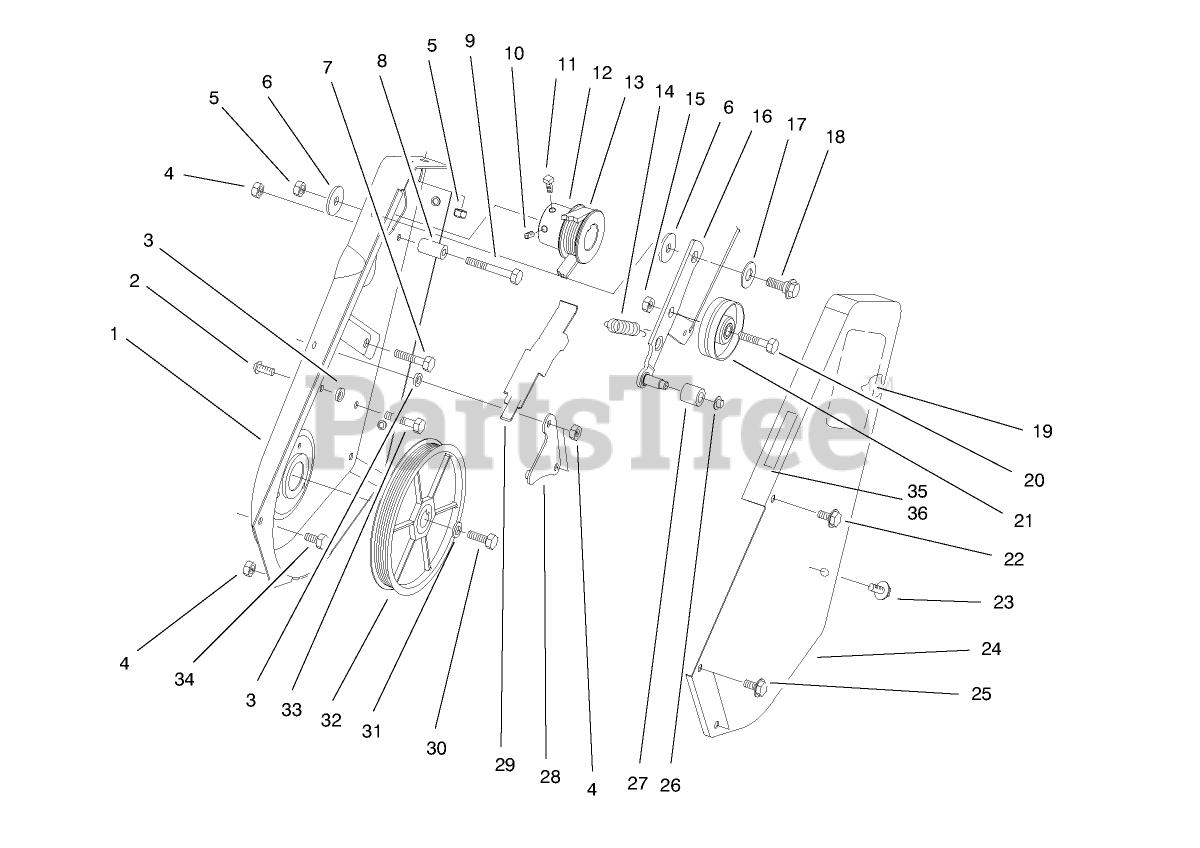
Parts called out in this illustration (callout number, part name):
2	SCREW-HSBH
3	SPACER-PLATE, PIVOT
4	NUT-LOCK, NI
5	NUT-LOCK, NI
6	WASHER-PIVOT
7	SCREW-HH
8	SLEEVE-GUIDE, BELT
9	SCREW-HH
10	SCREW-HSH
11	SCREW-SQH
12	ENGINE PULLEY
13	BELT - DRIVE
14	SPRING-EXTENSION
15	NUT-LOCK, CONE
16	IDLER ARM ASM
17	WASHER
18	SCREW-SHOULDER
19	DECAL
20	SCREW-HH
21	PULLEY-IDLER
22	SCREW-HWH, TAP
23	SCREW
25	SCREW-HWH
26	NUT-PUSH
27	ROLLER-BRAKE
28	PIVOT PLATE ASM
29	BRAKE-ARM
30	SCREW-HH
31	WASHER-BELLEVILLE
32	ROTOR PULLEY ASY
33	SCREW-HH
34	SCREW-SHH
36	DECAL-HOT
